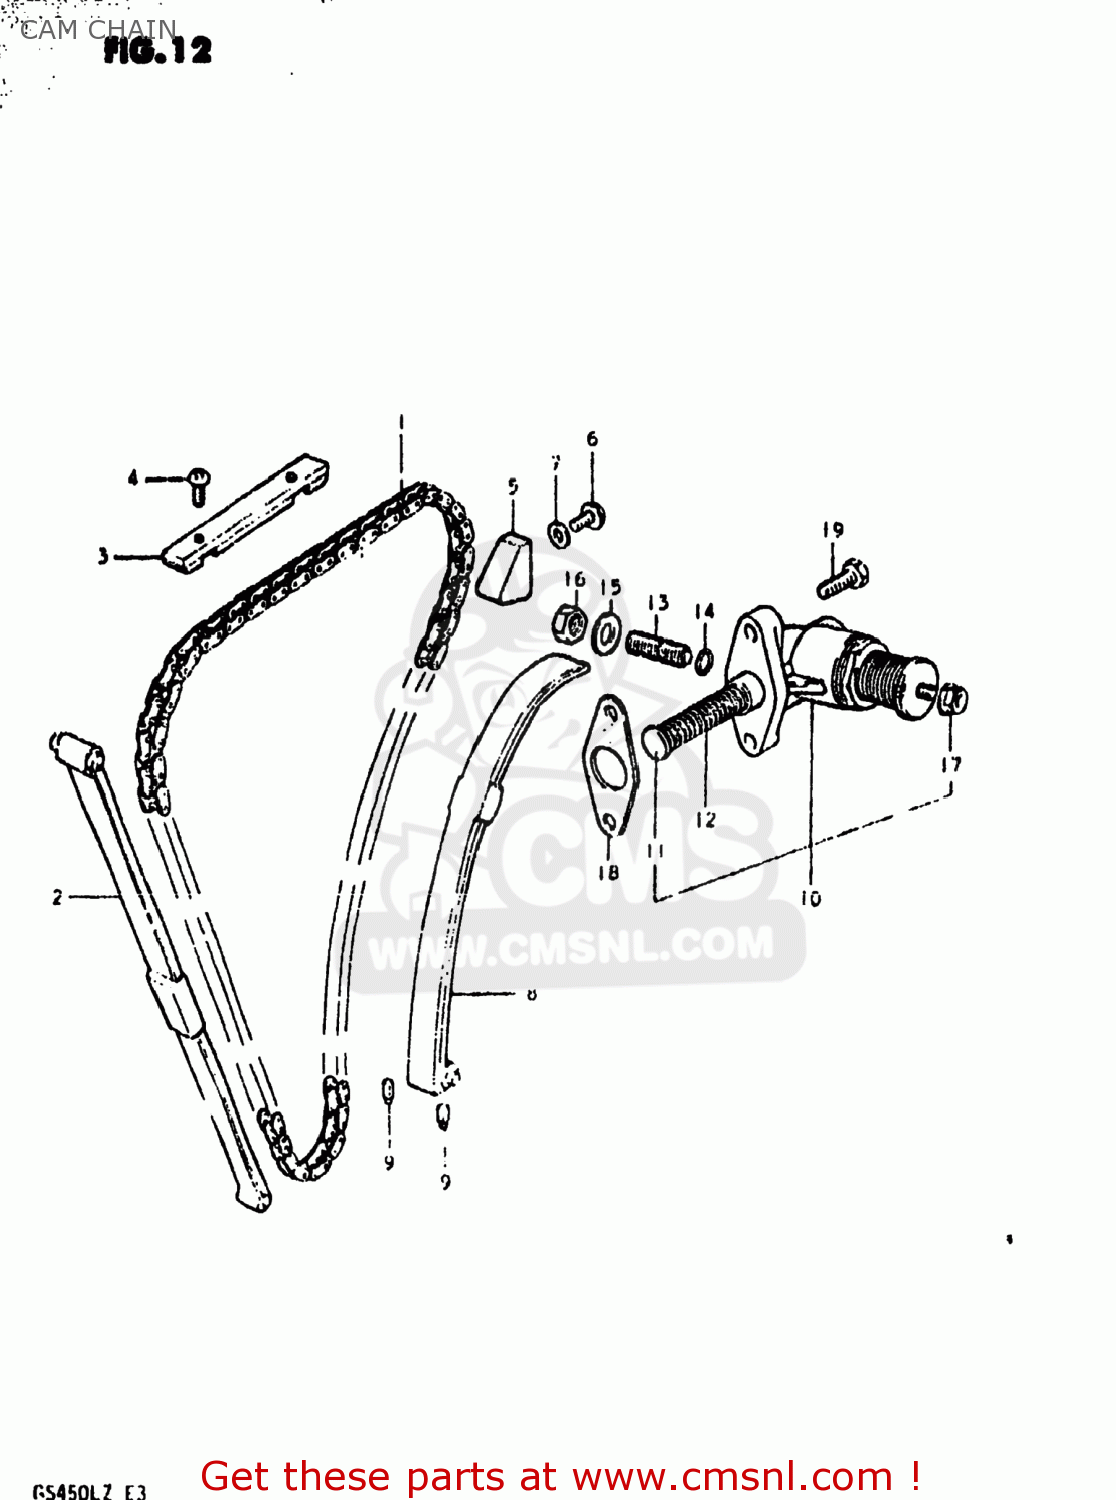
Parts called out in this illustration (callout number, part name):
1	CHAIN,CAMSHAFT DRIVE(120L)
2	GUIDE,CAM CHAIN NO.1
3	GUIDE,CAM CHAIN NO.3
4	SCREW
5	GUIDE,CAM CHAIN
6	BOLT
7	GASKET (NAS)
8	TENSIONER,CAM CHAIN
9	CUSHION,CAM CHAIN TENSIONER
10	ADJUSTER ASSEMBLY,TENSIONER
11	ROD,PUSH
12	SPRING
13	SCREW
14	O-RING
15	WASHER
16	NUT
17	NUT
18	GASKET,TENSIONER ADJUSTER (MCA)
19	SCREW (6X25)
